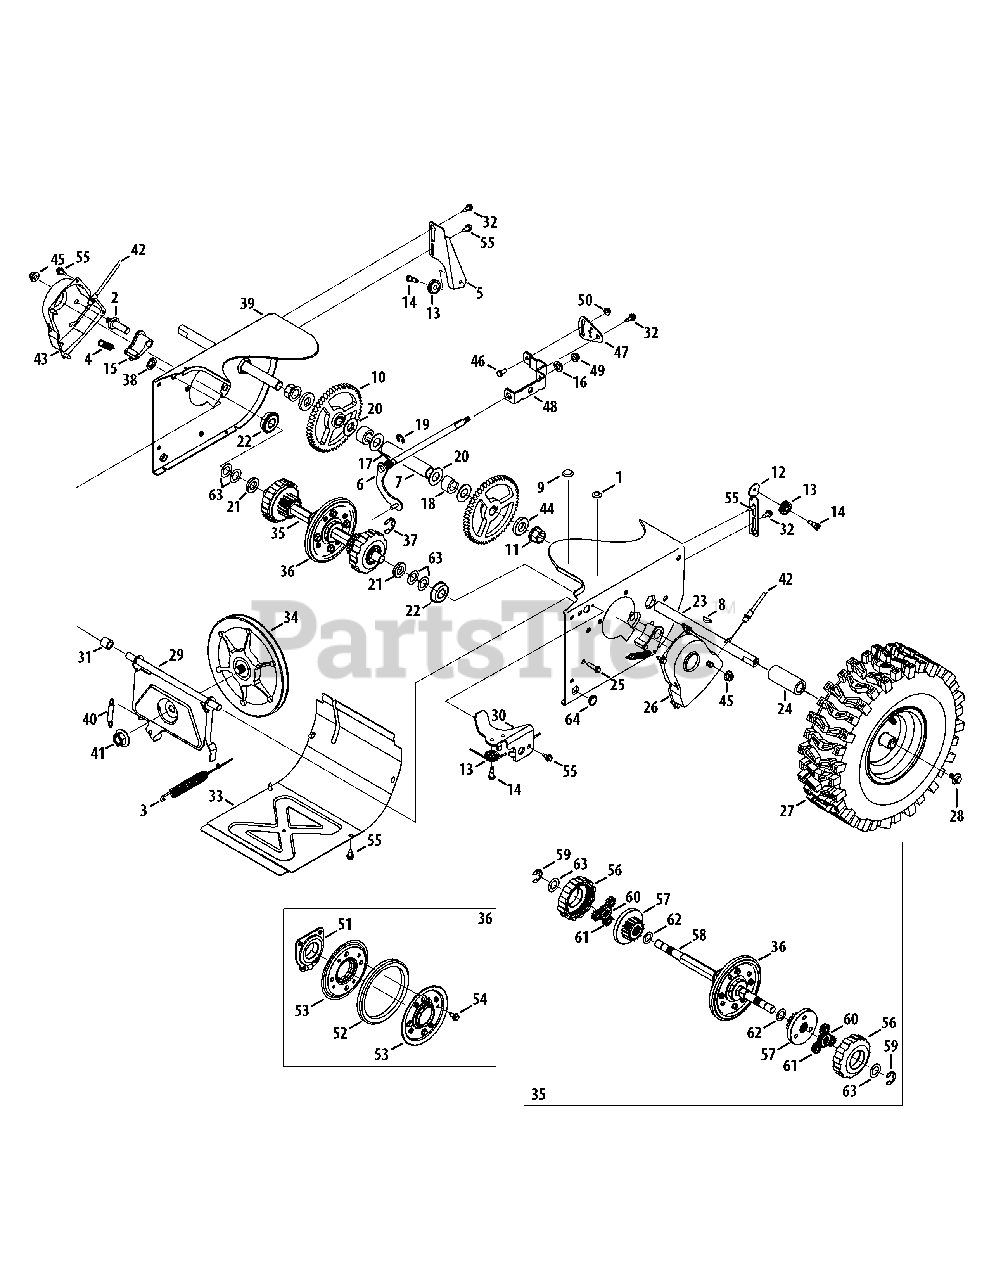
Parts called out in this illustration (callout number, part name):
1	Plug, 3/8 ID
2	Actuator Shaft
3	Drive Clutch Cable
4	Extension Spring
5	Drive Clutch Cable Guide Bracket
6	Shift Rod Assembly
7	Axle Support Tube
8	Hi Pro Key
9	Plug, 1/2 ID
10	Gear, 56T
11	Hex Flange Bearing
12	Auger Clutch Cable Guide Bracket
13	Cable Roller
14	C Screw, 1/4-28 x 0.375
15	Dogg Assembly - LH
15	Dogg Assembly - RH
16	Washer, Flat
17	Torsion Spring, .750 ID x .968 Lg.
18	Spacer
19	E Ring
20	Flat Washer, .76 x 1.49 x .06
21	Spacer
22	Ball Bearing
24	Spacer
25	TT Screw, 1/4-20 x 1.0
26	Shaft Retainer - LH
27	Wheel Complete - LH
27	Wheel Complete - RH
28	Screw, 5/16-24 x 0.75
29	Friction Wheel Support Brkt. Assy.
30	Auger Cable Guide Bracket
31	Spacer
32	Shoulder Screw
33	Frame Cover
34	Friction Wheel Disc Assembly
35	Drive Shaft Assembly
36	Friction Wheel Assembly
37	Retainer Ring
38	Speed Nut
39	Wheel Drive Frame
40	Extension Spring
41	Flange Nut, 5/8-18
42	Steering Cable
43	Shaft Retainer - RH
44	Axle Spacer
45	Flange Lock Nut, 3/8-16
46	Hex Screw, 1/4-20 x .620
47	Speed Selector Pivot Bracket
48	Speed Selector Shift Bracket
49	Flange Lock Nut, 5/16-18
50	Flange Lock Nut, 1/4-20
51	Friction Wheel Bearing Assembly
52	Friction Wheel
53	Friction Plate
54	Screw, 5/16-18 x .750
55	AB Screw, 1/4-20 x 0.625
56	Gear Assembly, Plantry Ring
57	Carrier Assembly, Plantry Ring
58	Shaft, Strbl Drv Hex, .812
59	E-Ring
60	Gear, Sun, 18T
61	Gear, 12T
62	Washer, Thrust, .75 x 1.25 x .03
63	Washer, Flat, .67 x 1.174 x .02
